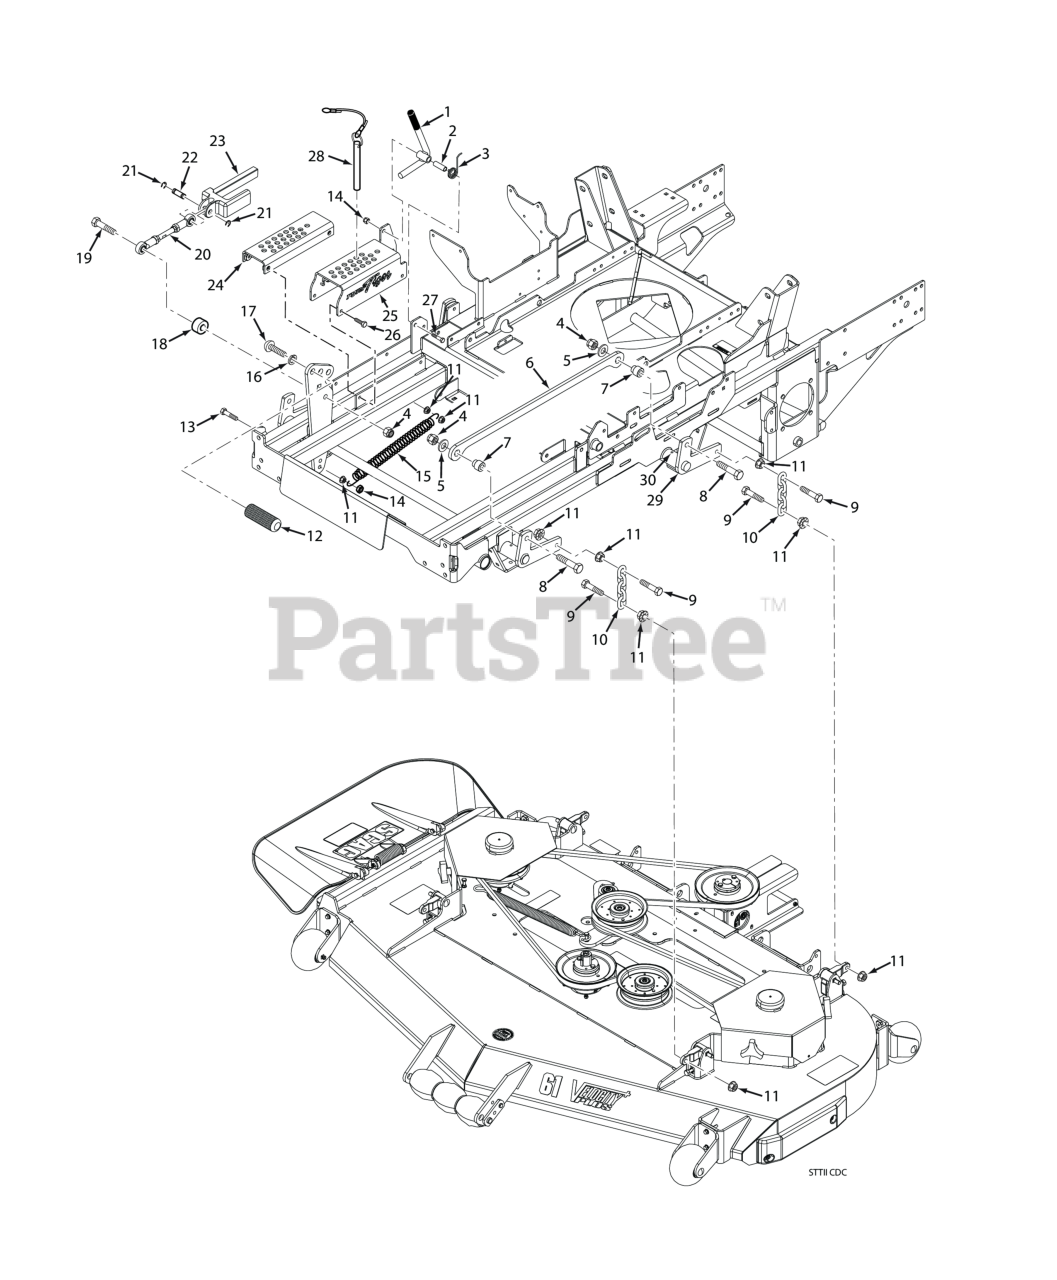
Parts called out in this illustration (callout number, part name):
1	Deck Latch Weldment w/Grip
2	Bushing, .502 O.D.
3	Spring, Torsion - Lever Return
4	HEX LOCKNUT, ELASTIC STOP, 1/2-13
5	Flat Washer, 1/2 (.562 x 1.375 x .109)
6	Pivot, Deck Link
7	Pivot, Deck Link
8	Bolt, Hex Head 1/2-13 x 2-1/4"
9	Bolt, Hex Head, 3/8-16 x 1-1/2"
10	Footplate
11	NUT, 3/8-16 SERRATED FLANGE HEX HEAD
12	Foot Pedal, Height Adjustment
13	Bolt, Hex Head 3/8-16 x 1-1/2" Grade 8 Black
14	Bolt, Hex Head 3/8-16 x 1" Ser. Flg.
15	Spring, Ext. Deck Lift
16	Lockwasher, 5/8" Spring
17	Capscrew, 5/8-11 x 1-1/2"
18	Spacer, Radiator
19	Hex Head Bolt, 1/2-13 x 2"
20	Linkage Assembly, Deck Lift
21	Retaining Ring, 1/2" Ext. "E"
22	Pin, Deck Lift
23	Slide, Height Adjust (INCL. 10,11,12)
24	Weldment, Lower Cutting Height
25	Adjustment Bracket, Cutting Height Upper
26	Bolt, Hex Wshr Head 5/16-18 x 1-1/4"
27	Bolt, Hex Head 3/8-16 x 2-1/4" - 61"
28	Lanyard, Deck Height Pin Assembly
29	LIFT BELLCRANK WLMT, LH REAR
30	GREASE FITTING, STR. 1/4-28 SELF TAP.
